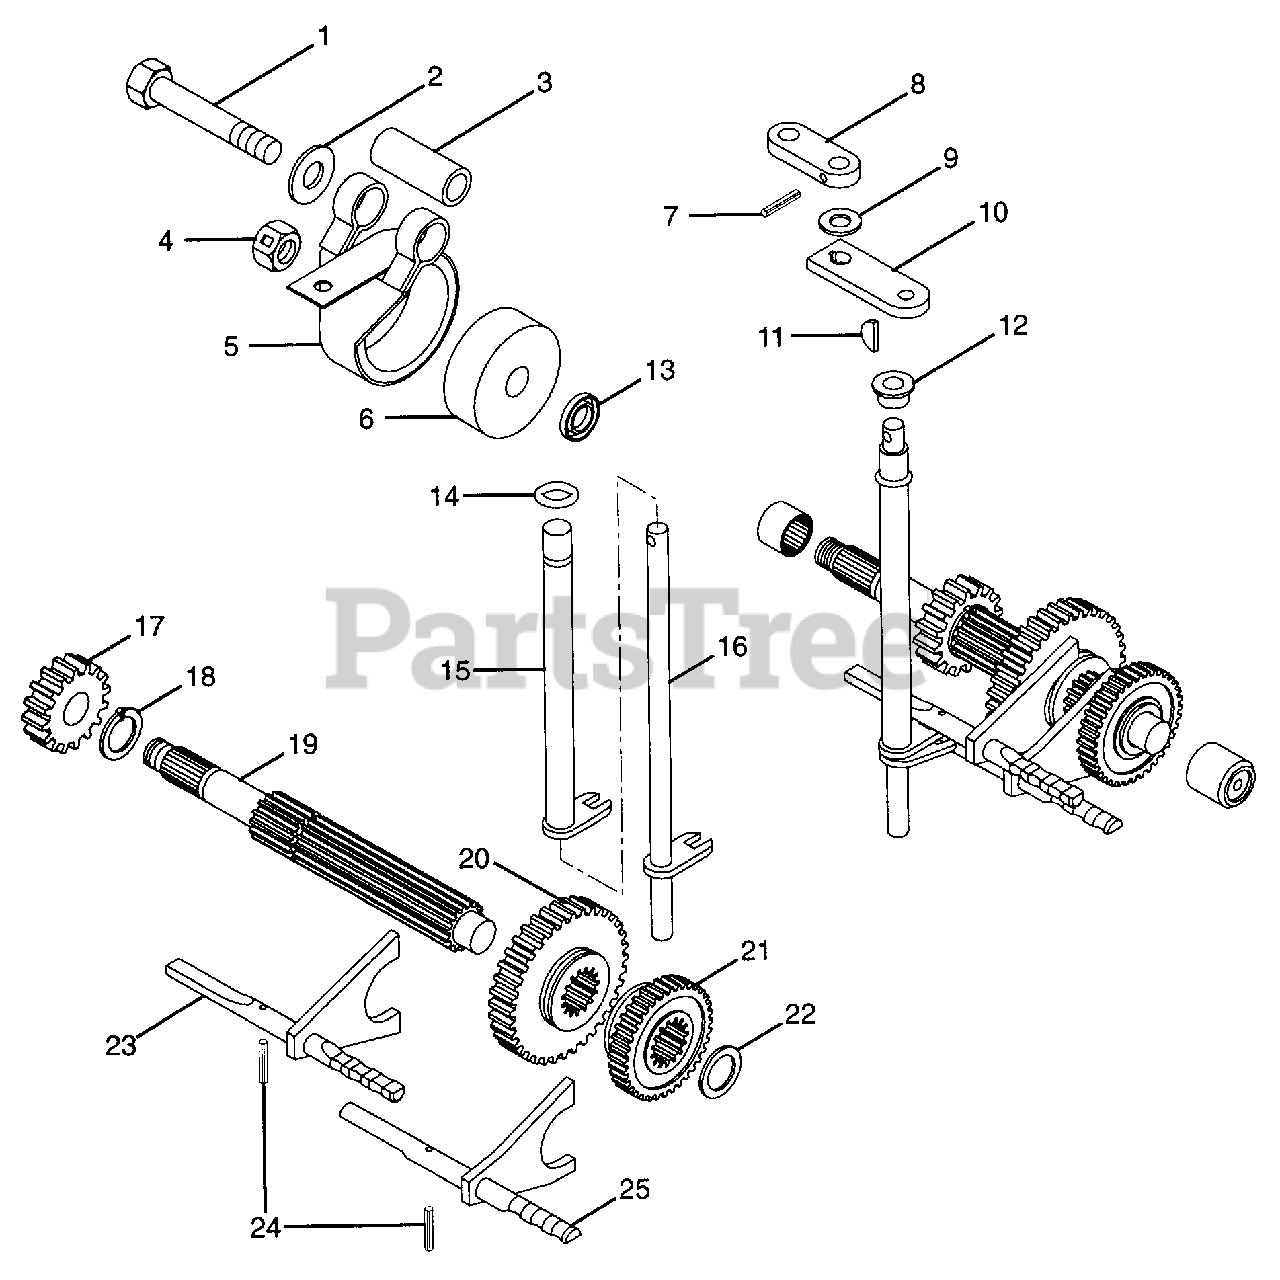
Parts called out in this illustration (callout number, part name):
1	Bolt-Hex .50-13 x 2.75 Grade 5
2	Washer-Flat-Steel .531 x 1.062 x .095
3	Bushing-Sleeve .550 x .750 x 2.06
4	Nut-Locking-Center .625-11 Grade 2
5	Assembly-Brake Band
6	Drum-Brake
7	Pin-Roll .187 x 1.000
8	Arm-Shifter
9	Washer-Felt .437 x 1.000 x .031
10	Arm-Shifter
11	Key-Woodruff .13 x .38
12	Bushing-Flange .756 x 1.125 x .75
13	Seal .750 x 1.250 x .136
14	O-Ring .625 x .75 x .062
15	Weldment 1st & 3rd Shifter
16	Weldment 2nd & 4th Shifter
17	Gear 8 DP 16 Teeth x .850
18	Ring-Retaining External .920 x .125
19	Shaft-Slide Gear
20	Gear-Sliding 10 DP 36 T x .594
21	Gear-Sliding 10 DP 30 T x .594
22	Bearing-N-Thrust .752 x 1.24 x .093
23	Weldment-Rail Shift Fork 1 & 3
24	Pin-Roll .250 x .75
25	Weldment-Rail Shift Fork 2 & 4
